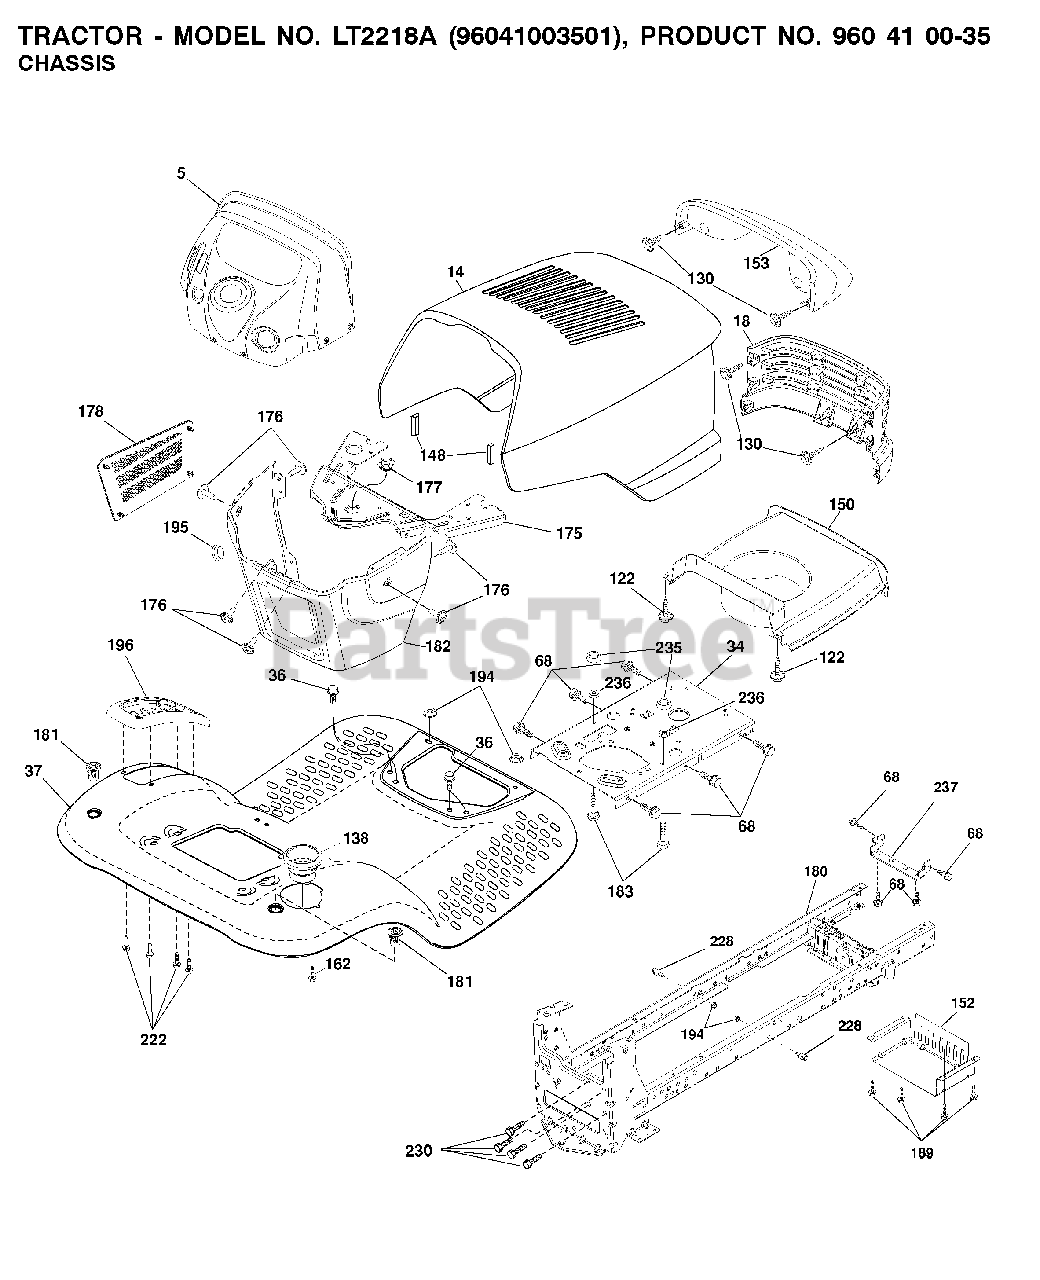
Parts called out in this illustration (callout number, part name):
34	PLATE.ENGINE.WELDED.CHASSIS
36	SCREW 5/16"
122	SCREW.WSHD.HEX10-32X5/8
130	SCREW
138	CUPHOLDER.TL.TEX.BLACK
148	EXTRUSION BUMPER
150	DUCT HOOD
152	SHIELD BROWNING
162	SCREW.HI-LO.CONSOLE
175	CROSSMEMBER.
176	SCREW.#10-24X5/8.RN.QU
177	BUSHING,STEERING
178	CARGO.ASM.NET.DASH.LOWER
180	CHASSIS
181	FEND/FTRST.PCH.CPH.NFW
182	DASH.LOWER.
183	BOLT.5/16-18X1-1/4 FULL.THREAD
189	SCREW
194	NUT LOCK HEX FLANGE 5/16-18
195	PLUG.HOLE.DASH.LOWER.12V.BLK
196	CONSOLE.ASM.DECK.LIFT.TLT.BLAC
222	SCREW.1/4-20X5/8
228	STUD.FASTNER.W/ANTI-ROTATE
230	SHOULDER BOLT 5/16-18TT
235	SPACER FENDER
236	NUT.CENTERLOCK.5/16-
237	BRKT.HOOD/MUFF.STEALTH
